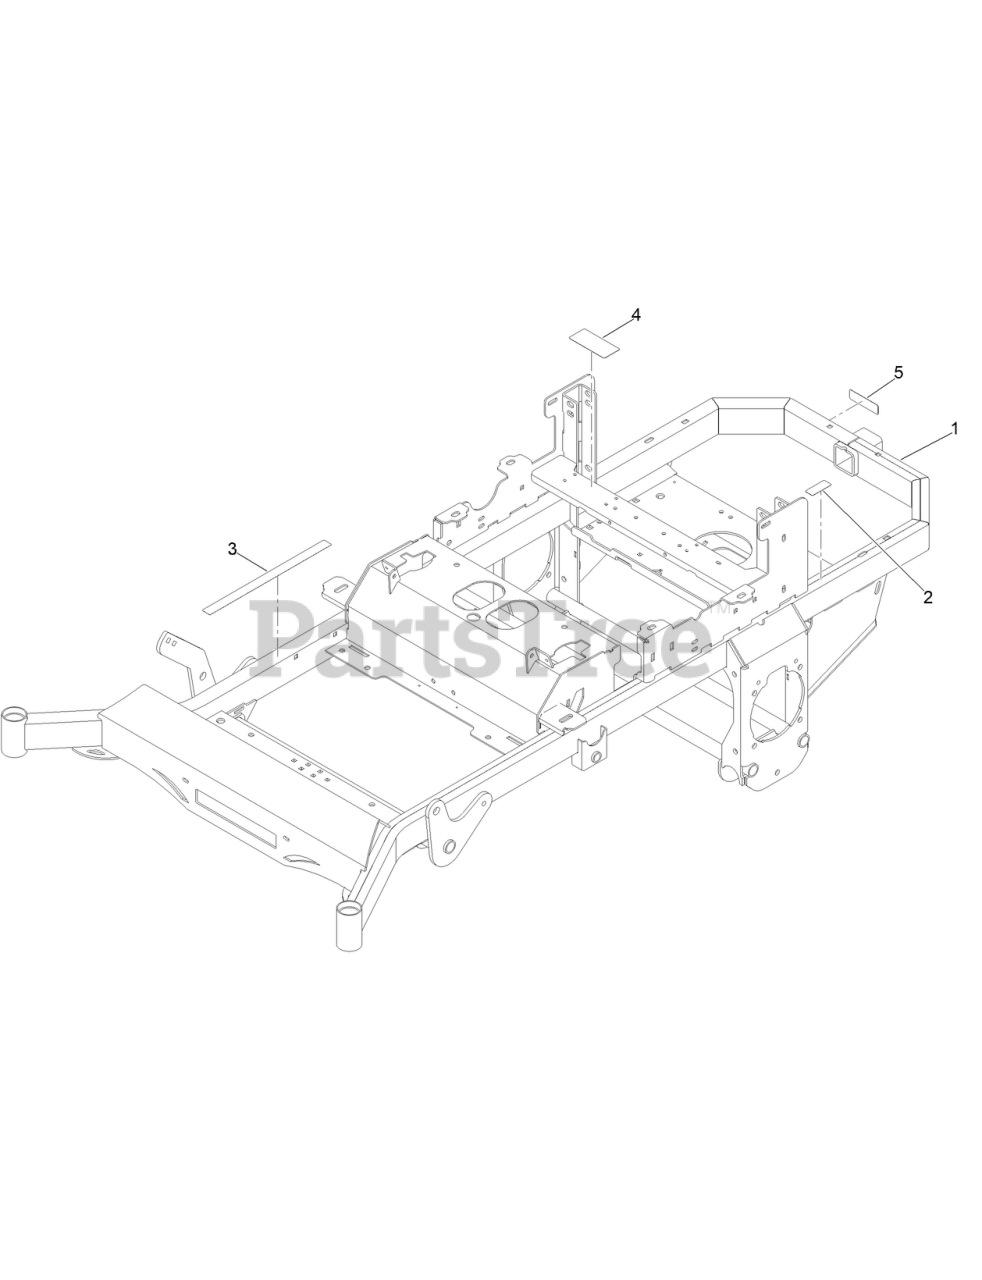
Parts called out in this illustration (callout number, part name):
1	FRAME ASM - KGZ PAINTED BLACK
2	DECAL-HOT SURFACE
3	DECAL-WARNING(AURORA)
4	DECAL-ROTATING FAN HAZARD
5	DECAL-HITCH
